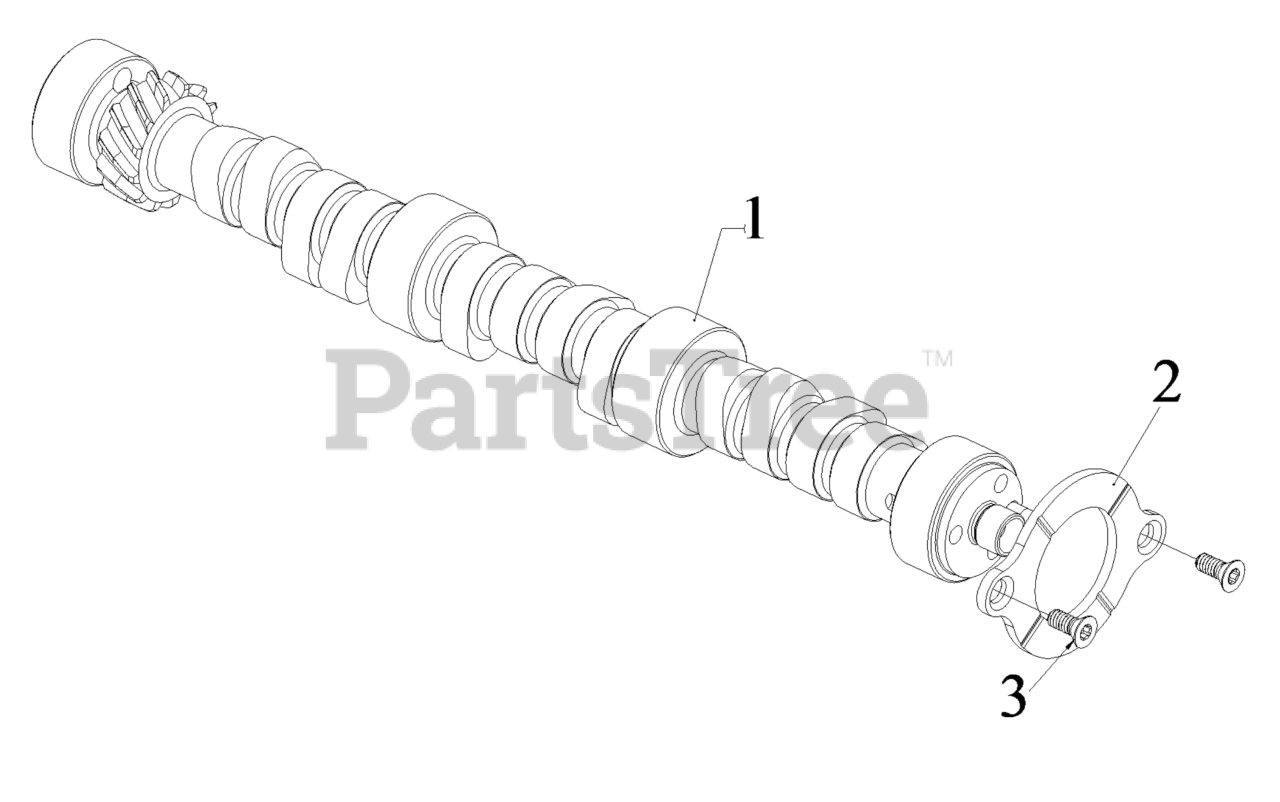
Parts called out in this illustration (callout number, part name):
1	*CAMSHAFT
2	*RETAINER, CAMSHAFT
3	*BOLT
